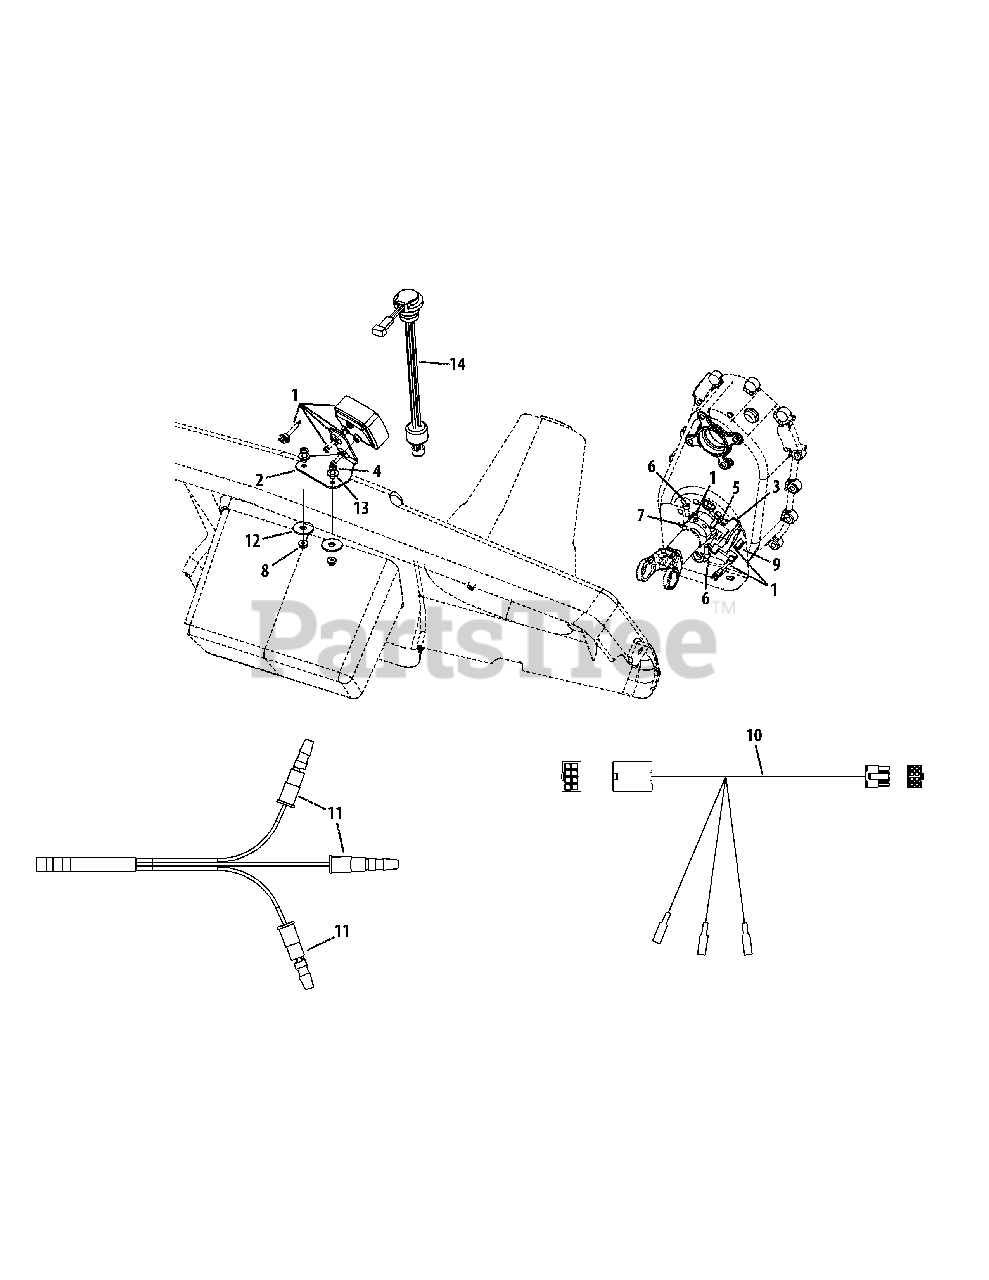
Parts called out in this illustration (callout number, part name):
1	Gauge Asm, UV
4	Scr, Mach, 1/4-20 x .750
5	Hhcs, 3/8-16 x .880
6	Scr, Cap, 1/4-20 x .62
7	Colr, Split, Half, 25/32 ID
8	Nut, Flglk., 1/4-20
9	Nut, Flglk., 3/8-16
10	Harn, UV, Speed, Fuel Gauge
11	Conn., Molex
12	Wash, Flat, .411 x 1.25 x .100
13	Wash, Flat, .344 x .688 x .065
14	Sensr, Fuel, Level, UV
